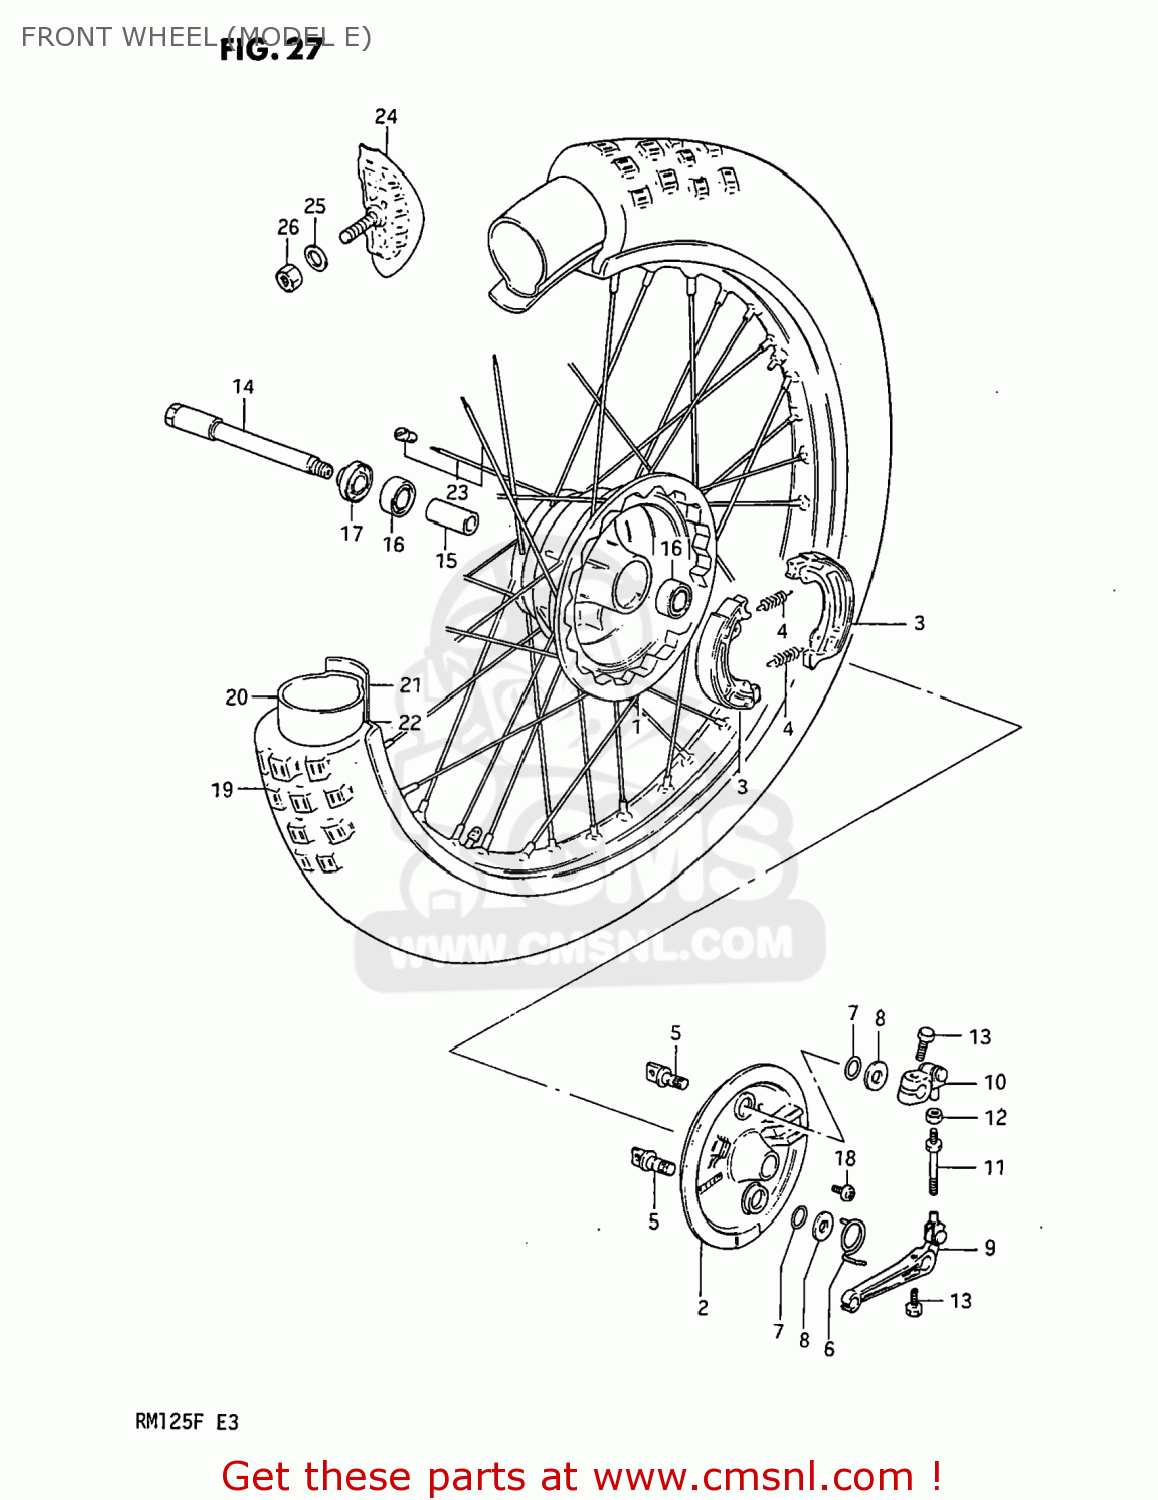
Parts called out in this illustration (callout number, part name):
1	DRUM,FRONT HUB
2	PANEL,FRONT HUB
3	SHOE,BRAKE (MCA)
4	SPRING
5	CAM,FRONT BRAKE
6	SPRING
7	O-RING (D:2 ID13.8)
8	WASHER (14.2X22X1)
9	SHOE SET,BRAKE
10	LEVER ASSY, BRAKE CAM, NO.2
11	ROD,BRAKE CAM LEVER CONNECTION
12	NUT 6MM
13	BOLT
14	AXLE,FRONT
15	SPACER,FRONT HUB BEARING
16	BALL BEARING 15X35X11
17	SPACER,FRONT AXLE,RIGHT
18	SCREW
19	TIRE,FRONT
20	TUBE,INNER
21	PROTECTOR,WHEEL,INNER
22	RIM,FRONT WHEEL (1.60X21)
23	SPOKE SET,FRONT
24	STOPPER,BEAD
25	WASHER
26	NUT 8MM
